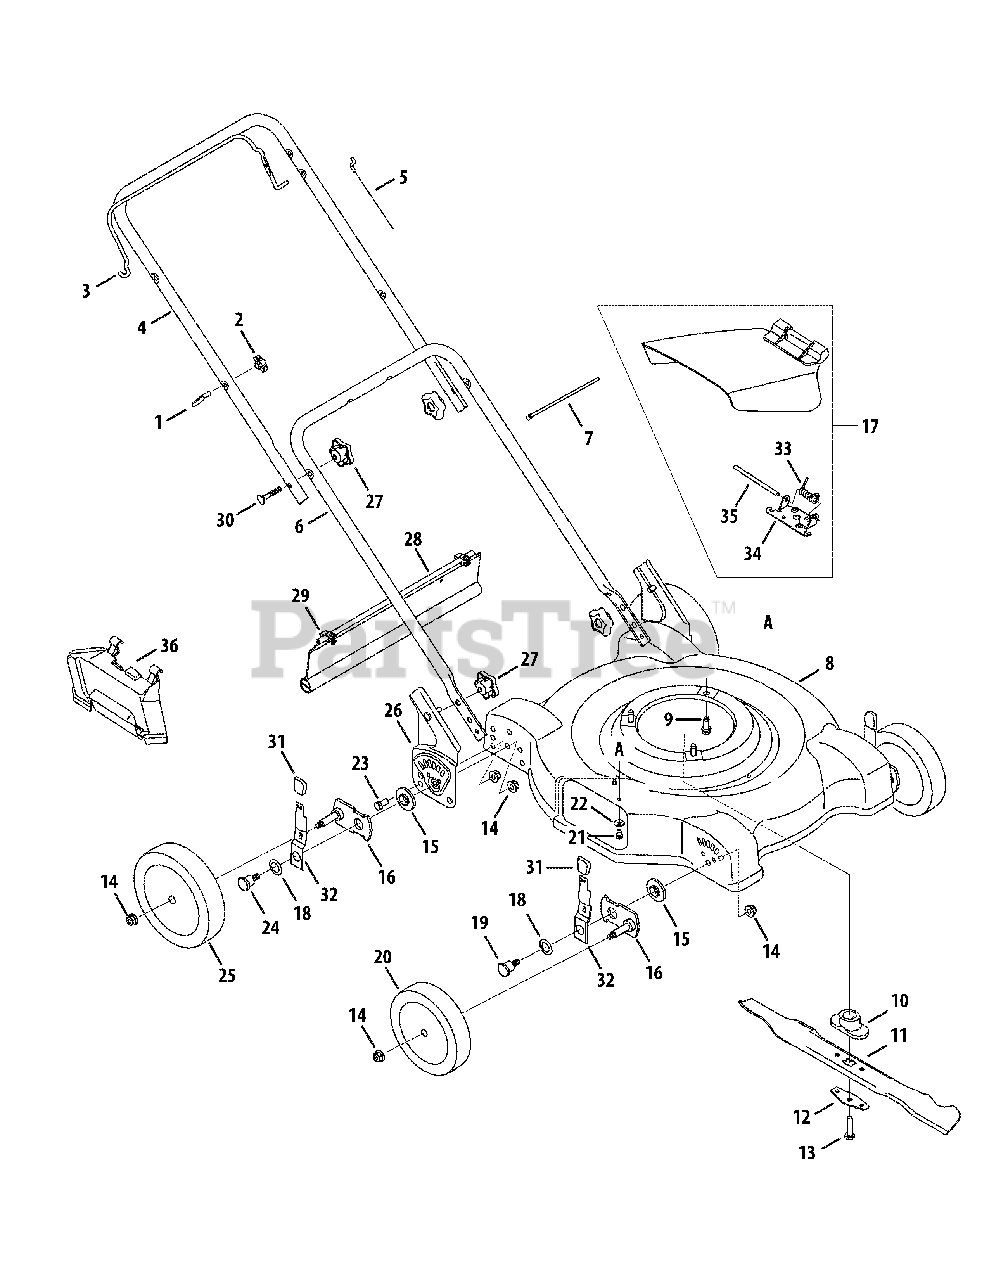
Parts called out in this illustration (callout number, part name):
1	Eye Bolt
2	Wing Nut
3	Blade Control Handle
4	Upper Handle
5	Control Cable
7	Cable Tie
8	Deck Assembly, 22"
9	TT Screw, 3/8-16 x 1.0
10	Blade Adapter
11	Standard Blade, 22"
11	Mulching Blade, 22"
12	Blade Bell Support
13	Screw, 3/8-24 x 1.5
14	Lock Nut, 3/8-16
15	Height Adjuster Bearing
16	Pivot Arm
17	Hinged Chute Deflector Assembly
18	Bell Washer, .760 OD x 1.25 OD
19	Shoulder Screw
20	Front Wheel, 7 x 1.8, Bar
21	TT Screw, 1/4-20 x .5
22	Bell Washer, .265 ID x .75 OD
23	Screw, 3/8-16 x .75
24	Shoulder Screw
25	Rear Wheel, 8 x 1.8, Bar
26	Handle Bracket Assembly, RH
26	Handle Bracket Assembly, LH
27	Star Knob
28	Trailshield
29	Hinge Clip
30	Carriage Bolt, 5/16-18 x 2
31	Knob
32	Lever
33	Torsion Spring
34	Chute Hinge
35	Hinge Pin
36	Mulching Plug
